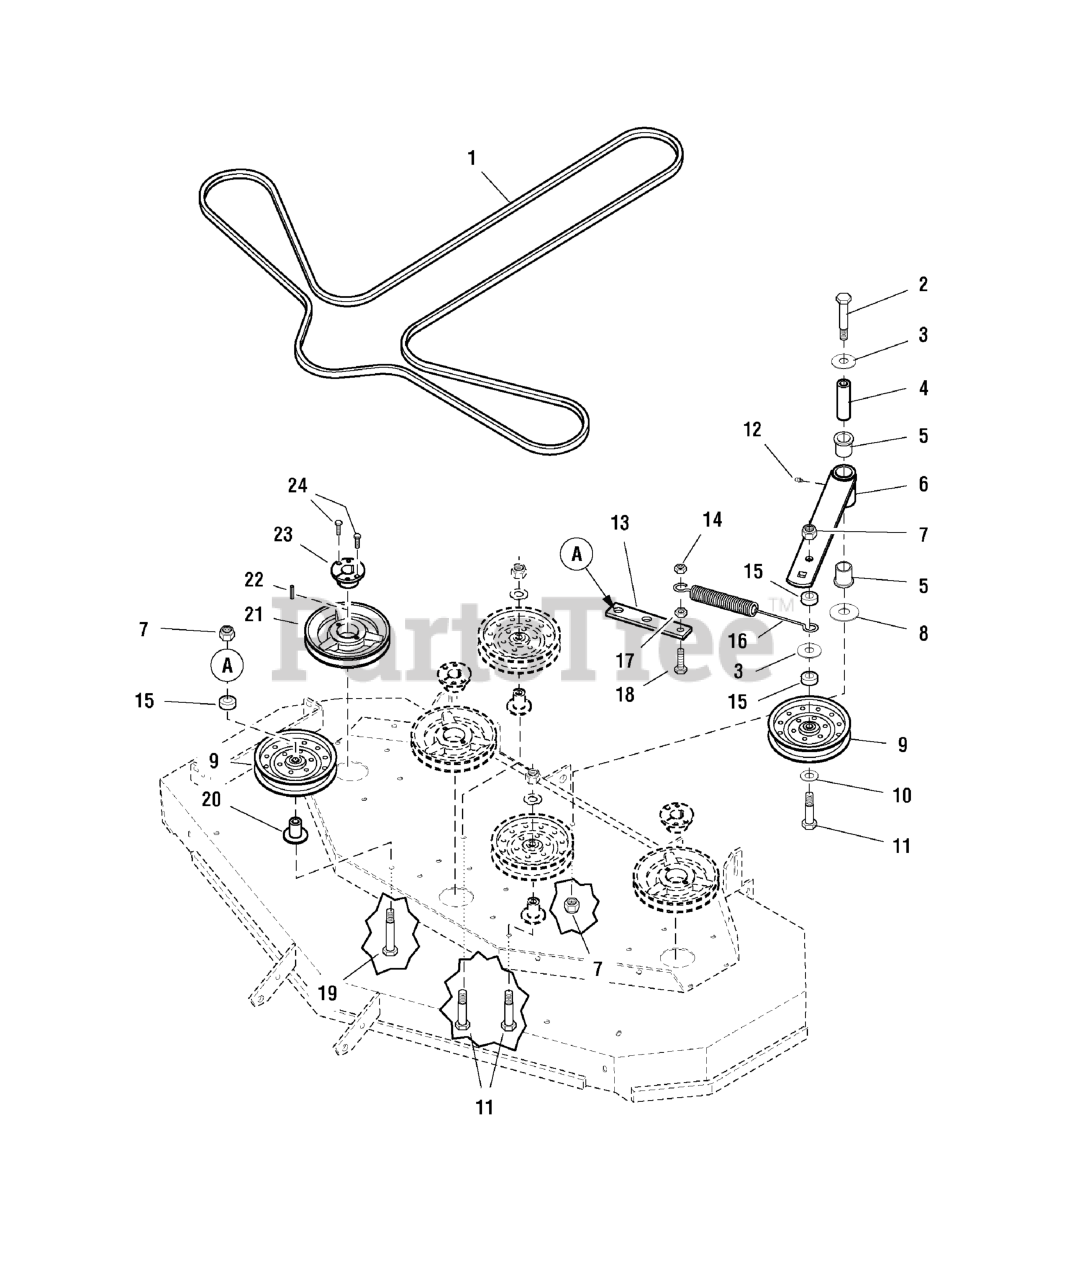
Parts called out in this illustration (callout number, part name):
1	BELT, 5V, 175.90EL, LG ARAMID, WRPD, RC
2	BOLT, 1/2-13 x 4-1/2
3	WASHER, 1/2" USS
4	SPACER, .52 x 1.00 x 3.50
5	BUSHING, FLANGE
6	IDLER ARM
7	NUT, 1/2-13 HEX NYLON LOCK
8	WASHER, 5/8" SAE
10	WASHER, 1/2 SAE
11	BOLT, 1/2-13 X 3" GD5 CZ
12	GREASE FITTING
13	MOUNT, Idler Spring
14	NUT, 3/8-16 Hex Top Lock
15	SPACER, .52 x 1.00 x .44
16	SPRING, Extension, Swivel End
17	NUT, 3/8-16 Hex
18	BOLT, 3/8-16 X 1-1/4" GD5 CZ
19	BOLT, 1/2-13 X 3-1/2, HEX HD, GD5, CZ (SV)
20	IDLER MOUNT
21	PULLEY, Spindle
22	KEY, 1/4 SQ. X 1-1/4
23	BUSHING, Tapered Hub
24	BOLT, 1/4-20 X 1" GD5 CZ
